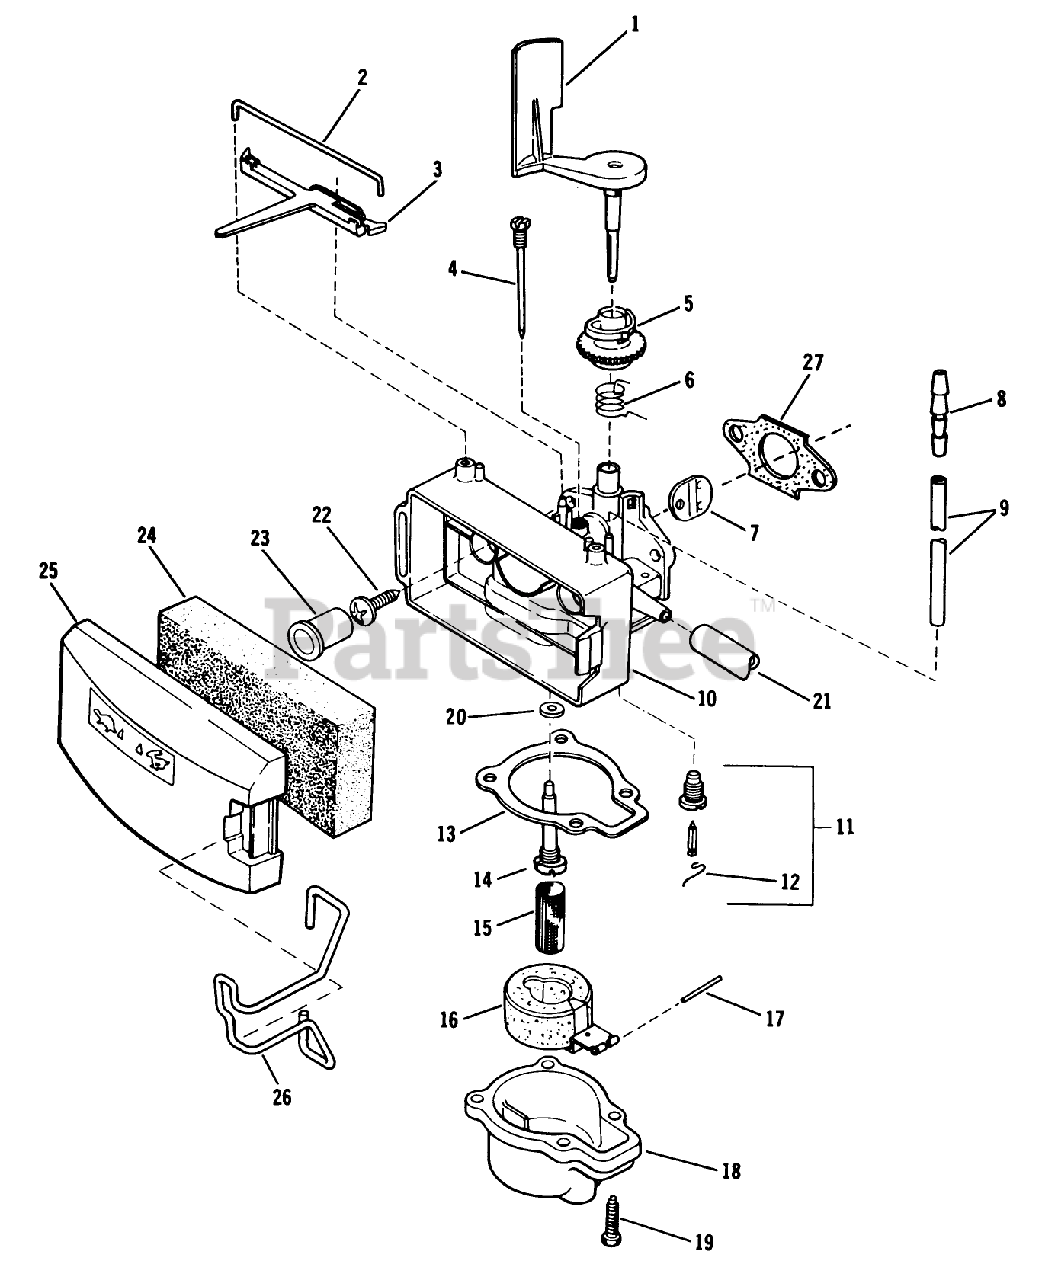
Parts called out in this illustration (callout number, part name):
2	RETAINER
3	LEVER S
4	NEEDLE ADJ. AY S
5	COLLAR-ADJUST, AIRVANE
6	SPRING,THROTTLE S
7	DISC S
8	REDUCER-CONNECTOR
9	TUBING S
10	CARB BODY S
14	NOZZLE SER KIT S
15	FILTER-FUEL VS
19	SCREW-HH
20	WASHER
21	GAS LINE
22	SCREW
26	RETAINER-COVER, FILTER
27	GASKET CARB S
